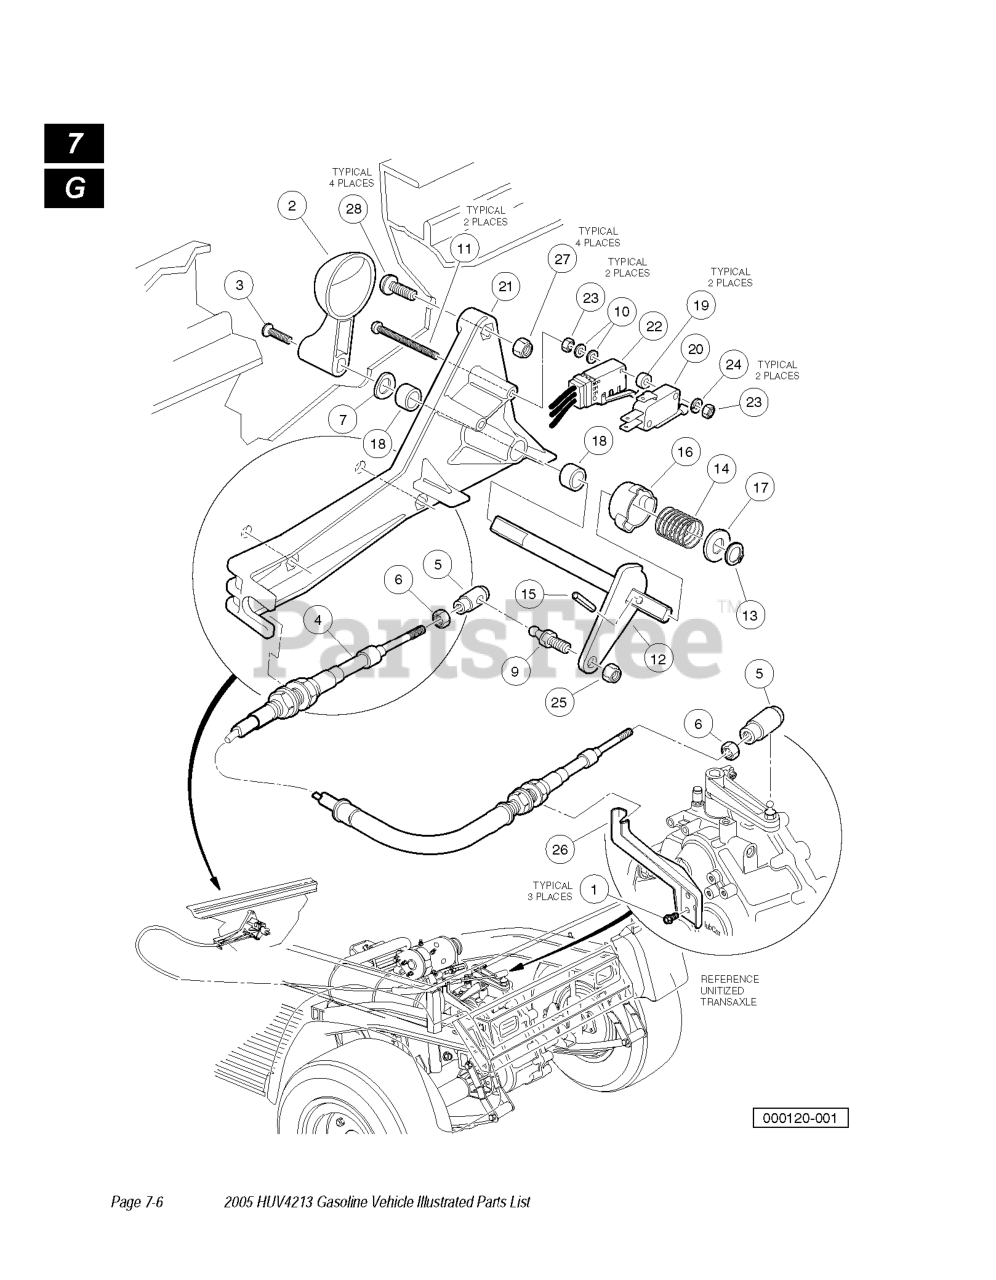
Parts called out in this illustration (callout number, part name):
1	SCREW HX TYP TT
2	HANDLE, FNR SWITCH
4	TRAN'S SHIFT CABLE ASM CA II
5	JOINT, #10-32 BALL
6	NUT, #10-32 HEX
7	WASHER, WAVE
8	F & R SHIFTER ASSEMBLY
12	F&R BELL CRANK WELDMENT
14	SPRING, FNR CAM
16	NEUTRAL LOCKOUT CAM KIT
18	BUSHING, SECONDARY WGHT SPLIT
20	SWITCH, LIMIT
21	SHIFTER BASE
22	SWITCH ASSY, SEALED LIMITER
23	NUT HEX MACHINE
24	LOCKWASH, # 4 HELICAL SPLIT
25	LOCKNUT, 1/4-28 NYLON INSERT
26	SHIFTER BRACKET
27	LOCKNUT, 1/4-20 NYLON INSERT
28	SCREW 1/4-20 X .75
